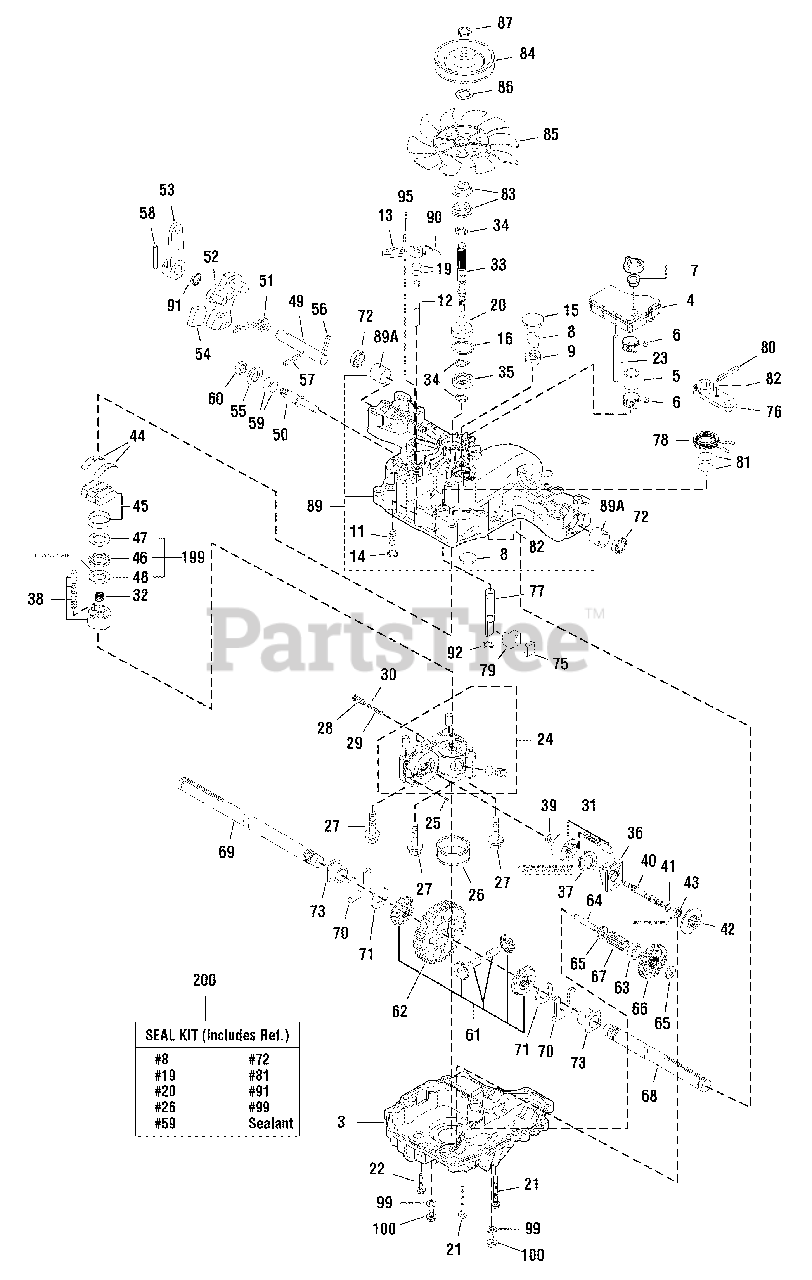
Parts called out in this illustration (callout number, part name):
3	*LOWER HOUSING
4	*RESERVOIR TANK
5	*TUBE
6	MINIATURE CLAMP
9	*HOLDER, Magnet
12	*SHAFT, Bypass
13	LEVER, Bypass
15	SEALING CAP
19	O-RING, 1A P10A
20	SEAL
21	SCREW, Tapping
22	*SCREW, Tapping
23	*SUPPORT
24	CENTER CASE, Complete
28	*IDS VALVE
31	CYLINDER BLOCK
32	SPRING, Pump
34	E-RING
35	BEARING
38	*CYLINDER BLOCK
40	SHAFT MOTOR
43	BEARING
44	THRUST METAL
45	SWASH PLATE COMPLETE
47	THRUST PLATE
48	THRUST PLATE
49	*CONTROL SHAFT
50	*FULCRUM, Eccentric
51	SPRING, Torsion
52	CONTROL ARM
53	CONTROL LEVER
54	JERKY PLATE
57	PIN, SPRING
58	PIN, Roll
61	KIT, Diff Pinion
62	*FINAL GEAR
63	*COLLAR, Final
64	*REDUCTION SHAFT
65	*WASHER
66	REDUCTION GEAR
67	FINAL PINION
68	AXLE SHAFT, Left
69	AXLE SHAFT, Right
70	THRUST WASHER
72	SEAL
75	SHOE, Brake
77	*SHAFT, Brake
78	RETURN SPRING
79	ACTUATOR, Brake
81	O-RING
83	SPLINE COLLAR
85	FAN
86	LOCK WASHER
89	*UPPER HOUSING
89A	*BUSHING
99	WASHER, Seal
100	*SCREW, Cap
199	*BEARING, Thrust
200	SEAL KIT, K46
